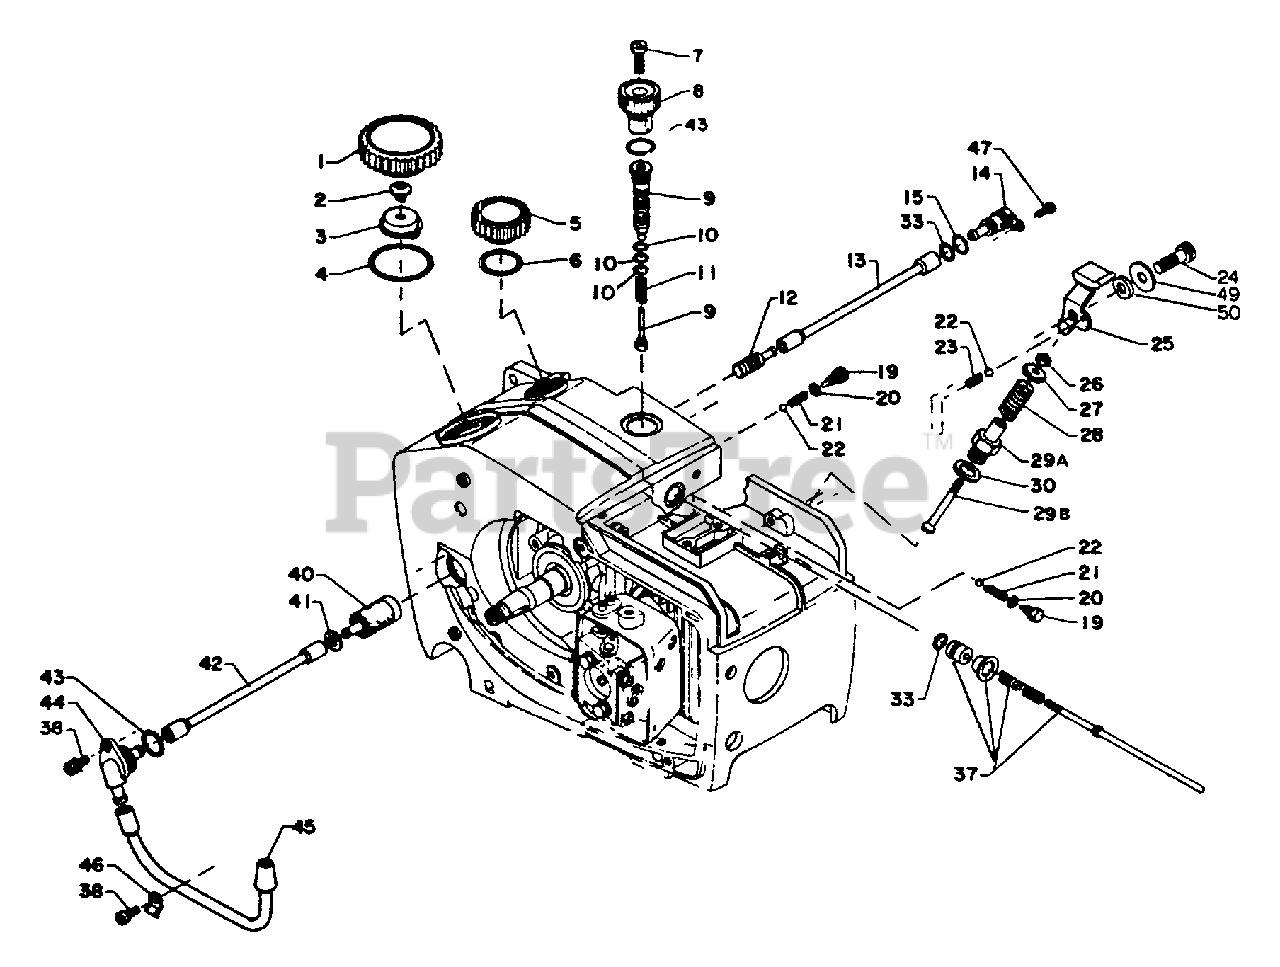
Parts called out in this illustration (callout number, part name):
1	CAP
2	VALVE, CHECK
3	HOLDER, VENT
4	O-RING 29
5	CAP, OIL TANK
6	O-RING 25 MM
7	LABEL - FUEL MIX
7	SCREW
8	LABEL - CHAIN OIL
9	AUTO-OILER ASSY
12	FILTER, OIL
13	PIPE, OIL - OUTER
14	CONNECTOR
15	O-RING 7 MM
19	ADAPTER, OIL PUMP
21	SPRING, VALVE
22	BALL
24	SCREW - 5×15
25	LEVER
25	DECOMPRESSION ASSY
33	O-RING 6 MM
37	PUMP ROD ASS'Y
38	SCREW 4×10
40	FILTER, FUEL
41	WASHER 5.5×12×0.8
42	PIPE, FUEL
43	O-RING 12 MM
44	CONNECTOR, PIPE
45	PIPE, FUEL
47	SCREW 3×8
49	WASHER 5.2×16×1.0
50	SPACER 5.2×8×2.1
